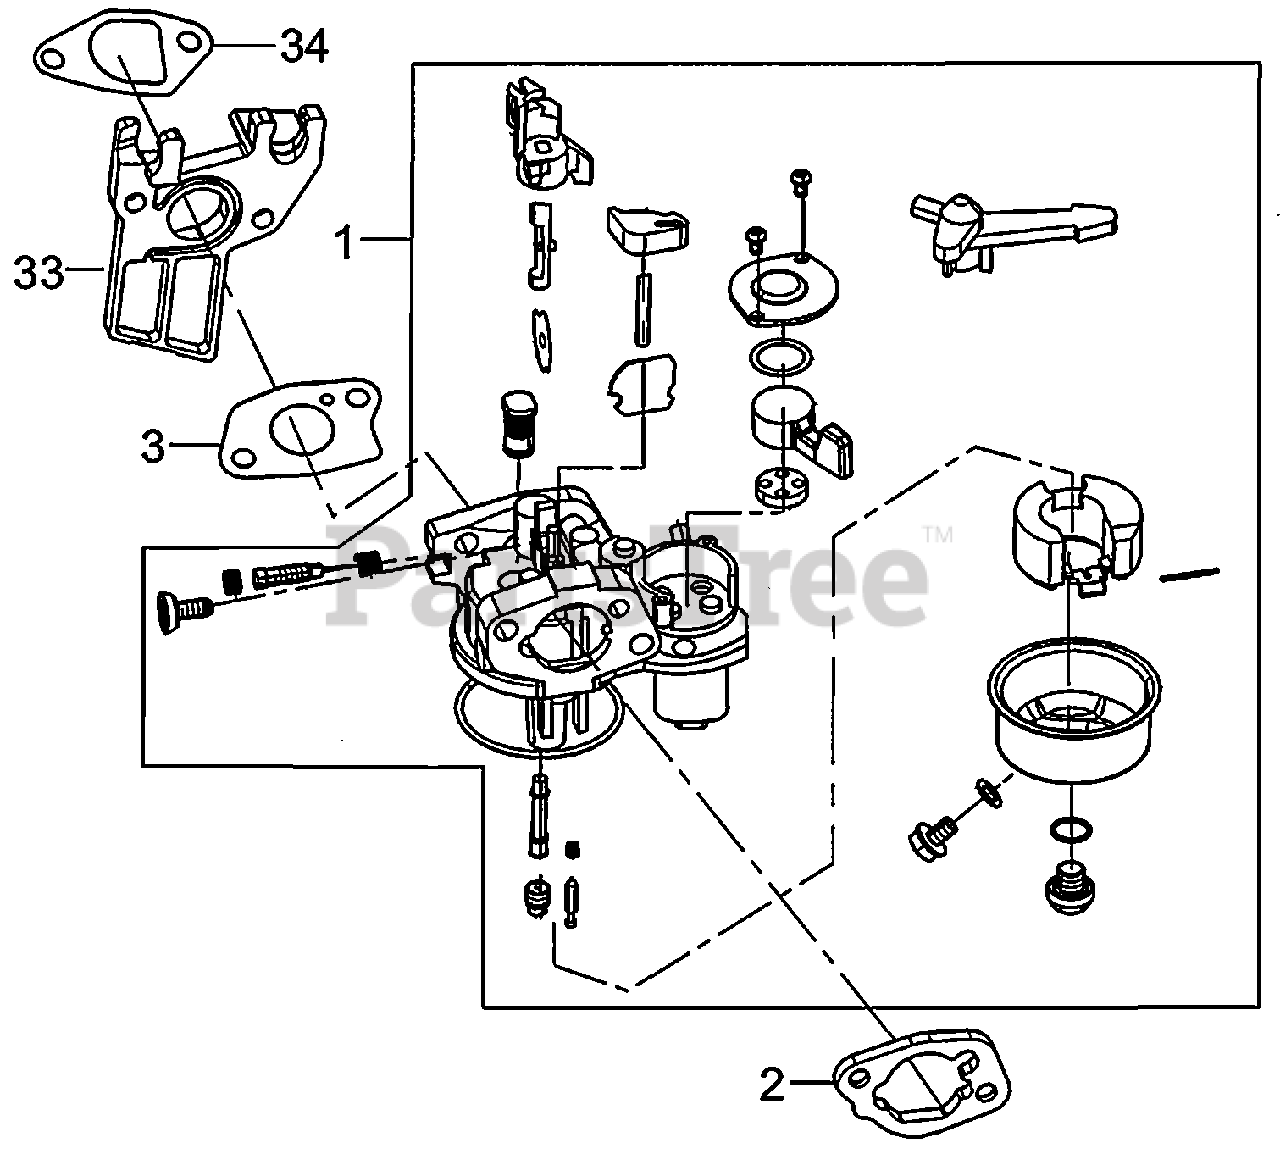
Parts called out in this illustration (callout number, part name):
1	CARBURETOR ASSY.
2	GASKET, AIR CLEANER
3	GASKET, CARBURETOR
33	PLATE, CARBURETOR INSULATOR
34	GASKET, CARBURETOR INSULATOR
